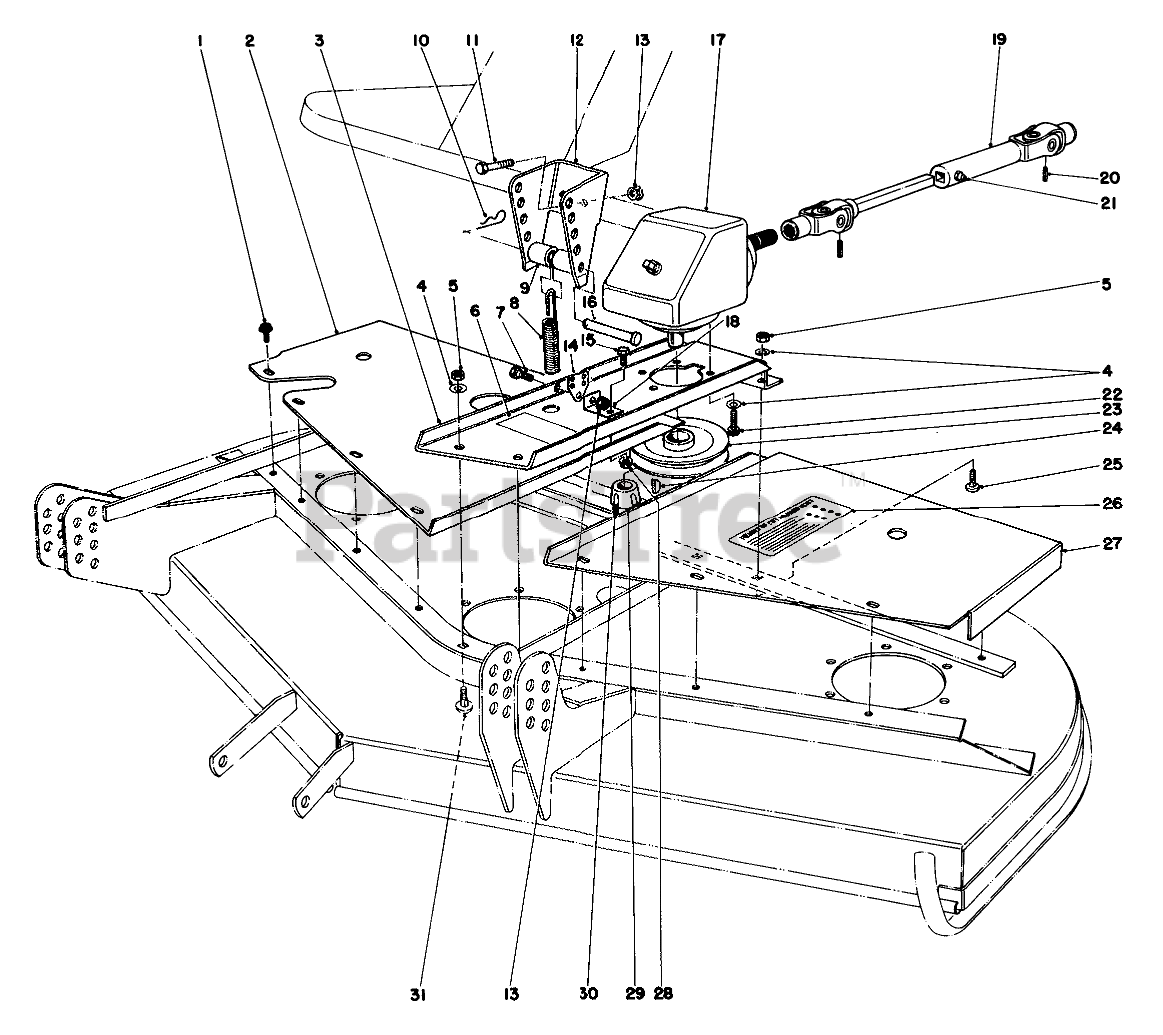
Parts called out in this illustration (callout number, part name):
1	SCREW-HHFTF
2	RH COVER WA R
3	Base-Bear Box
4	WASHER-LOCK
5	NUT-HEX
6	Decal-Caution
7	BOLT-SHOULDER
8	Spring-Extension
9	SPACER
10	PIN-HAIR
11	SCREW-HH
12	SPRING BRACKET R
13	NUT-HHF, WHIZ
14	SPRING END R
15	SCREW-HH
16	PIN-CLEVIS
17	GEAR BOX ASM
18	EXTENSION BRKT R
19	UNIVERSAL JOINT
20	PIN-ROLL
21	FITTING-GREASE
22	SCREW-HSH
23	PULLEY WA BO
24	KEY-WOODRUFF
25	BOLT-CARR
26	DECAL
27	LH COVER WA R
28	NUT-HF
29	BUSHING-LOCK, TAPER
30	SCREW-SET, HSH
31	SCREW-CARR
